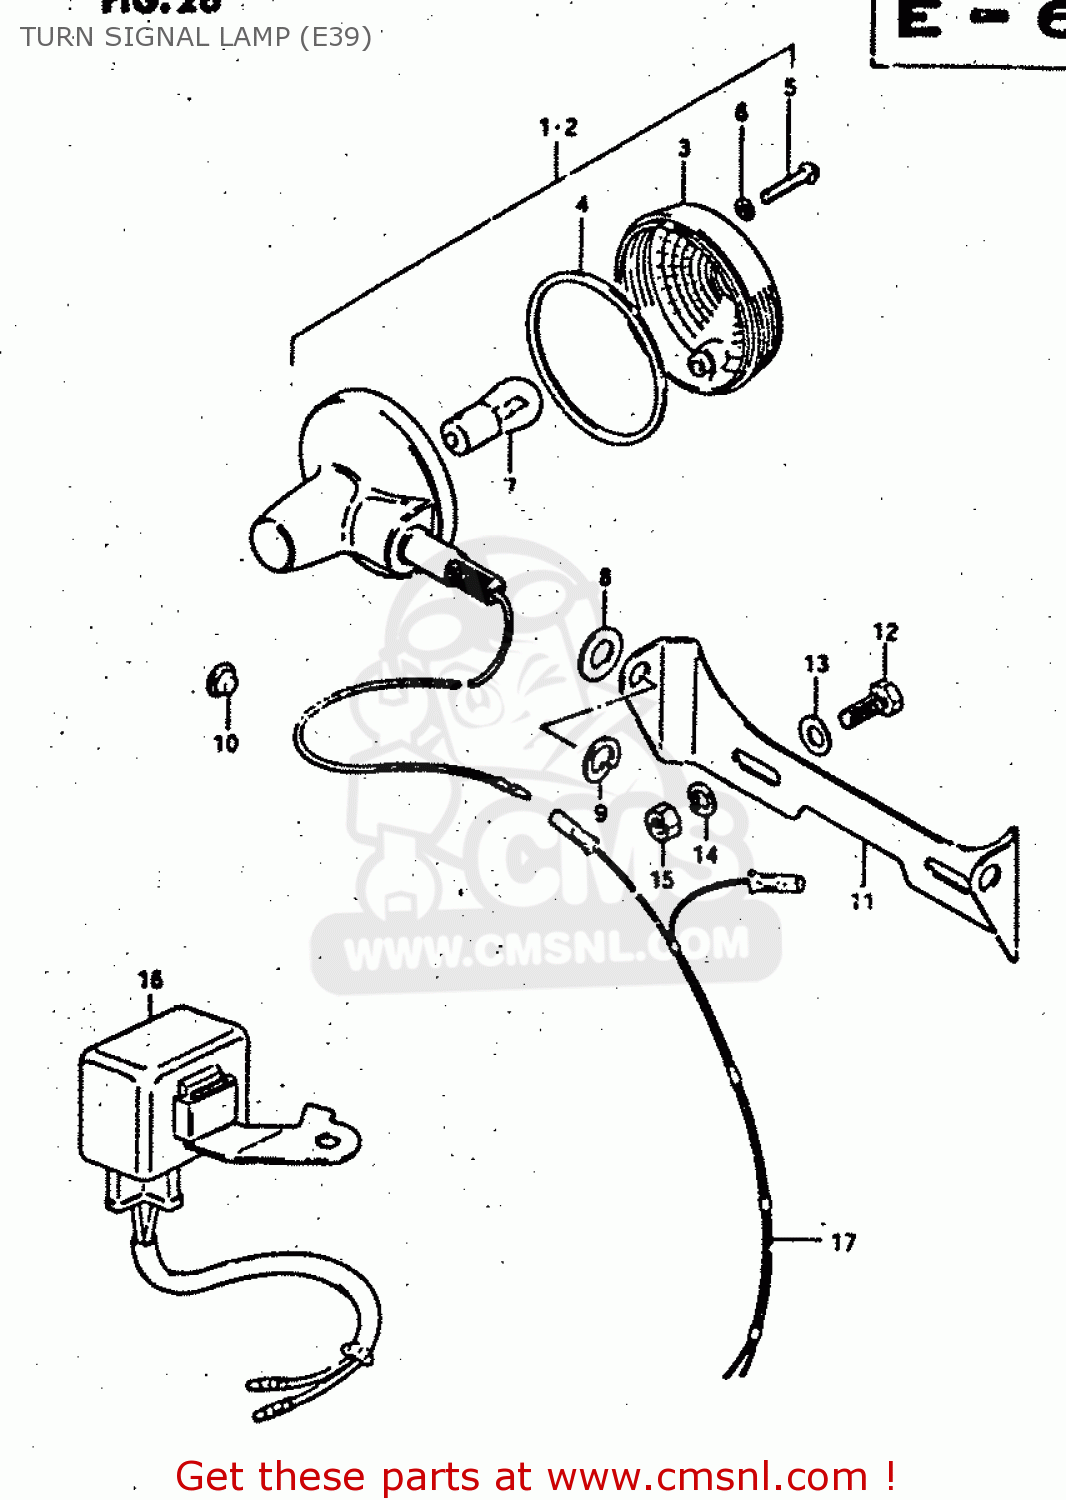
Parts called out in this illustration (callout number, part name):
1	LAMP, FRONT TURN SIGNAL
2	LAMP, REAR TURN SIGNAL
3	LENS
4	GASKET (NAS)
5	SCREW
6	GASKET (NAS)
7	BULB(6V/10W,STANLEY,A4117)
8	WASHER
9	LOCK WASHER
10	CAP(OD:10)
11	BRACKET, REAR TURN SIGNAL
12	BOLT, UPPER
13	WASHER(6.5X16X1.2)
14	LOCK WASHER
15	NUT
16	RELAY, TURN SIGNAL
17	LEAD WIRE, REAR TURN SIGNAL
